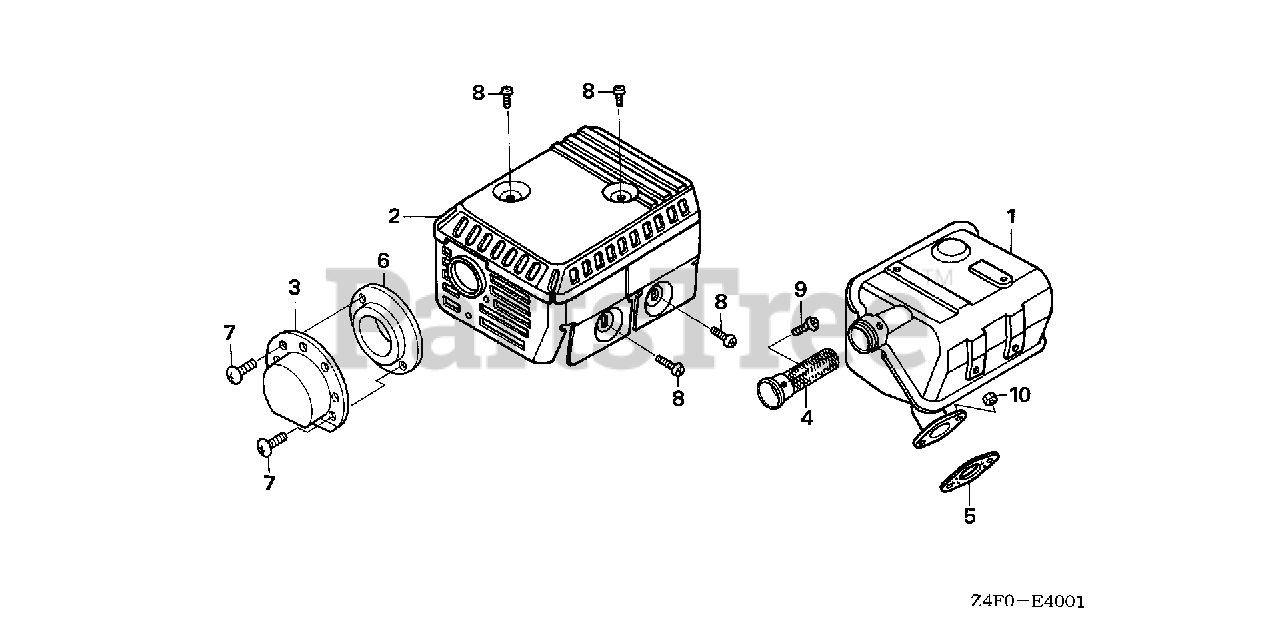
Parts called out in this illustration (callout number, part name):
1	MUFFLER (ARRESTER)
2	PROTECTOR, MUFFLER (STD) (BLACK)
4	ARRESTER, SPARK
5	GASKET, MUFFLER
8	SCREW, TAPPING (5X8)
9	SCREW, TAPPING (4X6)
10	NUT, HEX. (8MM)
